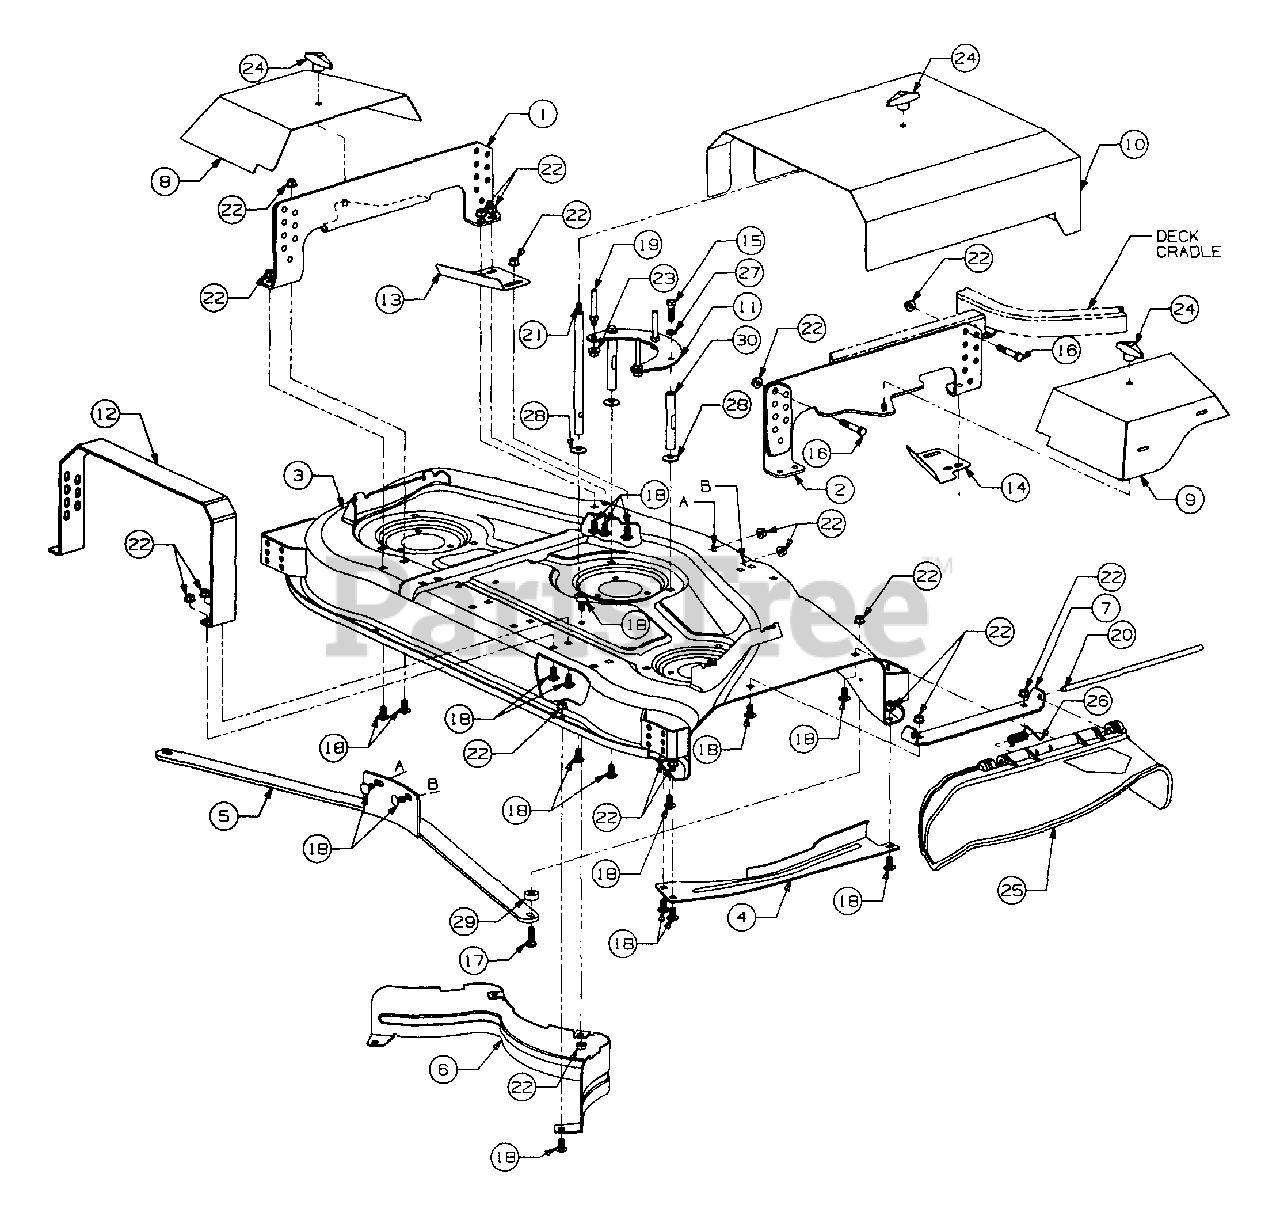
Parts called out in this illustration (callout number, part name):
3	Housing Assyw/Graphics, 48" Mower
11	Plate, Belt Guide Mtg
12	Bracket, Belt Cover Support
13	Plate, LH Filler
14	Plate, RH Filler
15	Screw, Hex Cap, 3/8-16 X 1.25 Lg GR5
16	Screw, Hex Cap, 3/8-16 X 2.25 Lg GR5
17	Bolt, Carriage, 3/8-16 X 1.25 Lg GR5
18	Bolt, Sht Nk Carriage, 3/8-16 X .75 Lg GR5
19	Stud, 3/8-16 X 2.68 Lg
20	Pin, Hinge, .375 X 12.55 Lg
21	Post, Belt CoverSupport
22	Nut, Hex Flanged Lock, 3/8-16
23	Nut, Hex Flange Lock, 3/8-16
24	Knob, Wing Nut
25	Deflector, Chute
26	Spring, Torsion
27	Washer, Lock, 3/8
28	Washer, Bell, 3/8 X 1.125 X .062 Thk
29	Spacer, Front Bar
30	Post, Belt Guide Mtg
